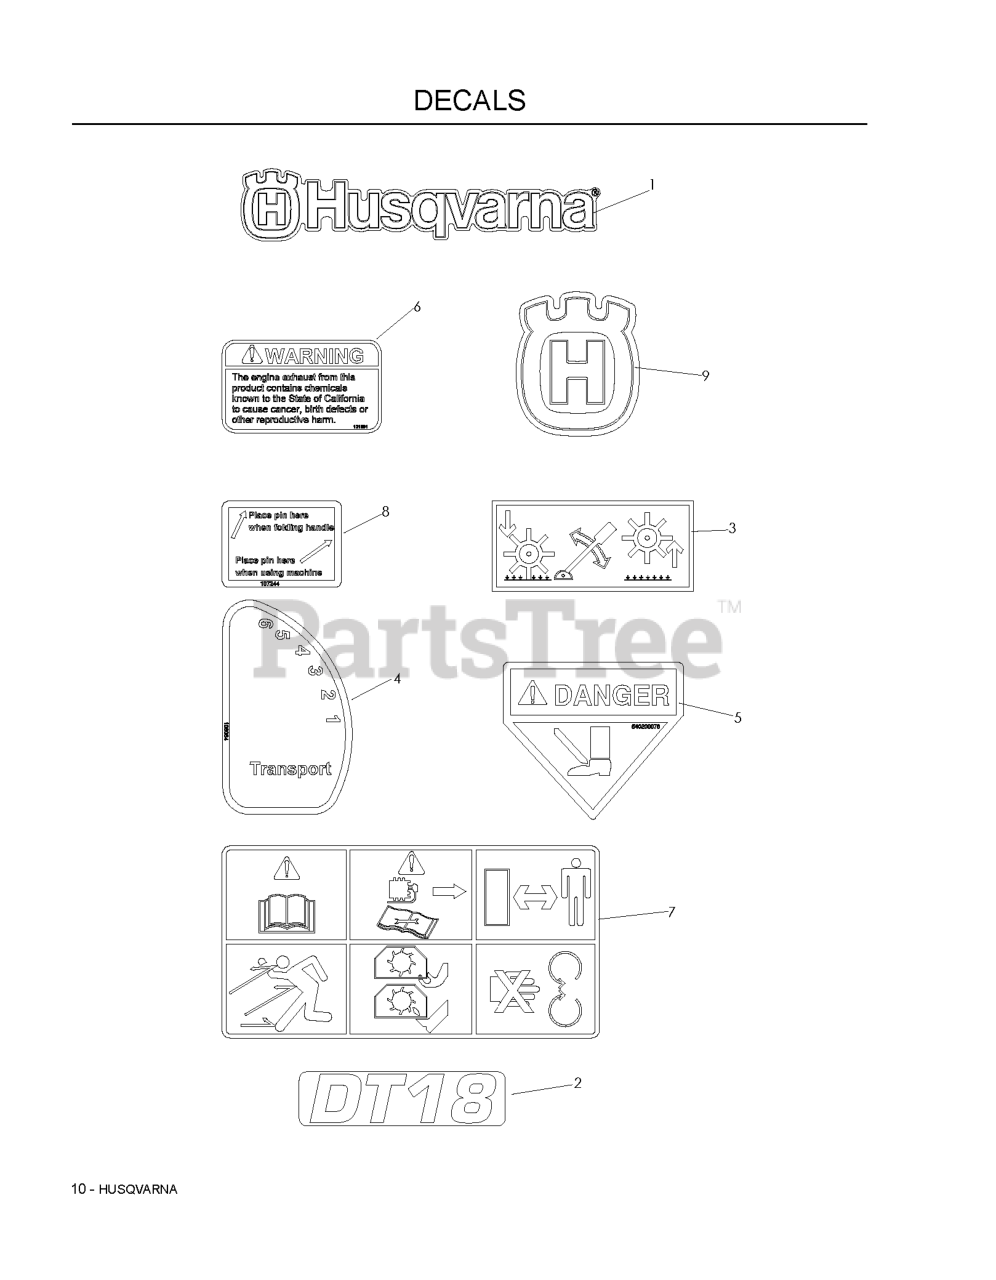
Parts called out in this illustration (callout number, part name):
1	DECAL.HOOD.LOGO.ORANGE.HUSQVAR
2	DECAL DT18
3	DECAL, HEIGHT ADJUST
4	DEPTH DECAL
5	DECAL, FOOT DANGER
6	DECAL, PROP. 65
7	DECAL, SAFETY GRAPHICS
8	DECAL, HANDLE PIN
9	DECAL, CROWN H 70MM
